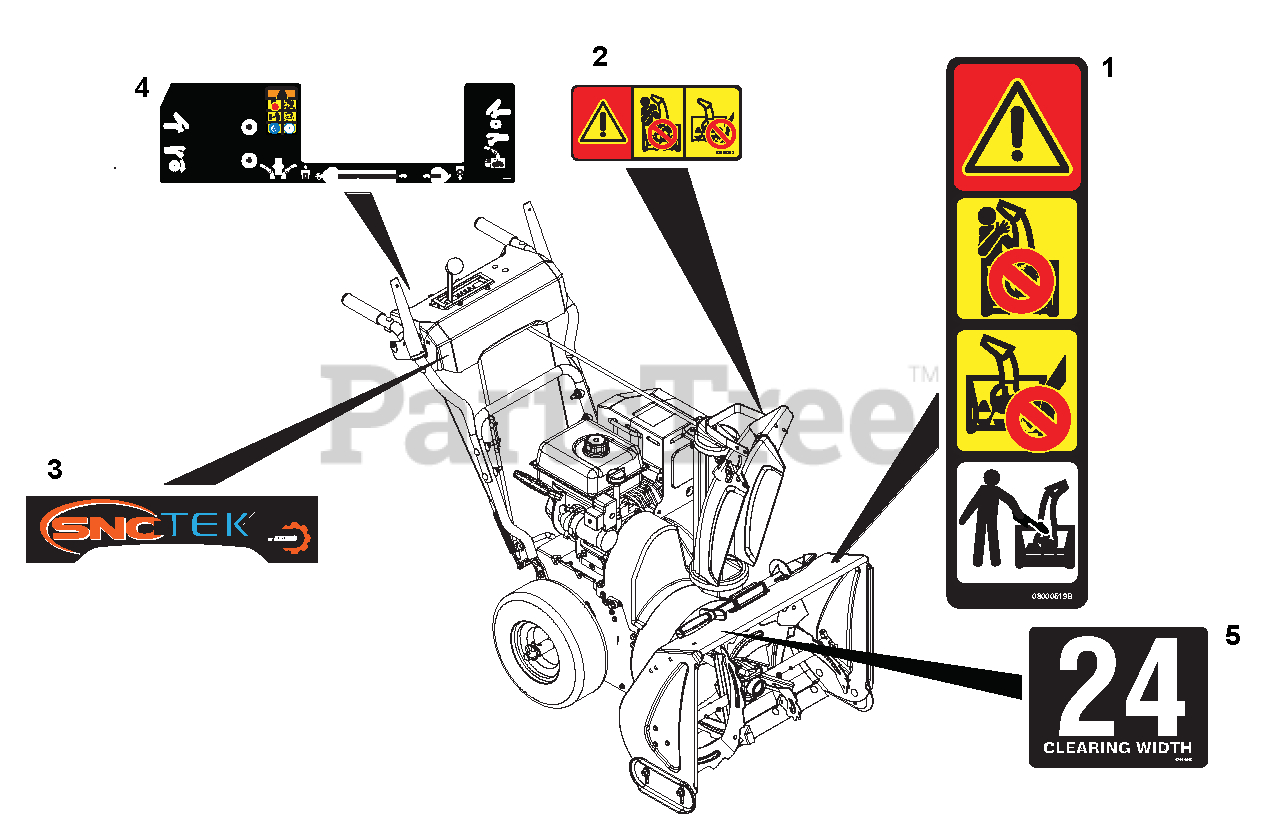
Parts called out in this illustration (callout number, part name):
1	DECAL, DANGER - ROTATING PARTS
2	DECAL, DANGER
3	DECAL, DASH - SNO-TEK
4	DECAL,CONTROL - COMPACT MANUAL
5	DECAL, HOUSING SNO-TEK 24
